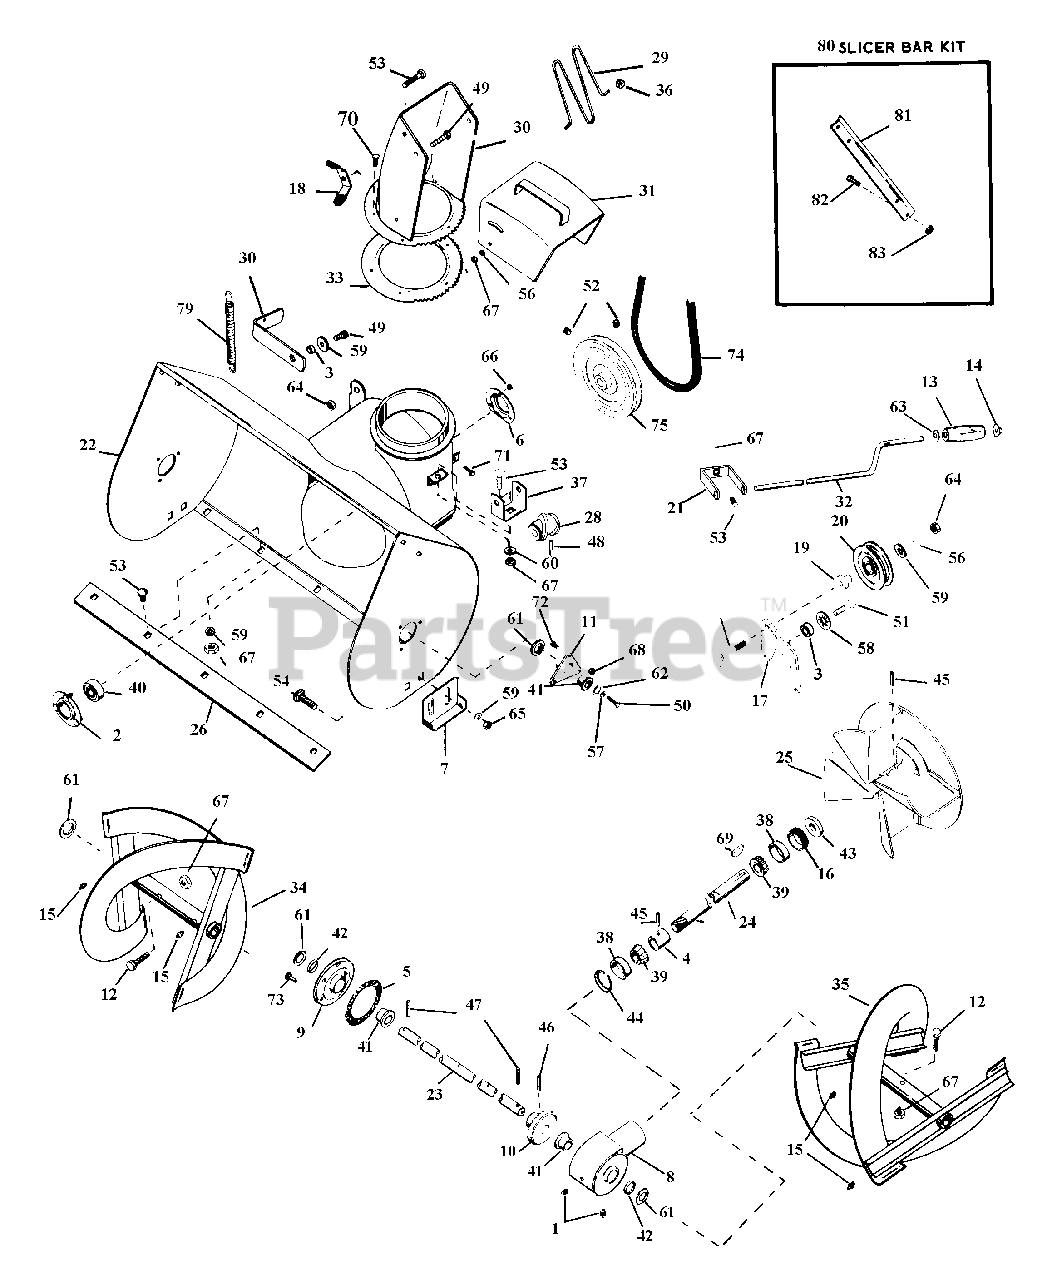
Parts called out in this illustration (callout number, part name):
1	PIPE PLUG
2	BEARING FLANGE
3	SPACER BUSHING .5 X .32 X .21
4	BEARING SPACER
6	BEARING FLANGE
7	RUNNER
8	CASE, GEAR - C.I.
9	GEAR CASE FLANGE
10	HELICON GEAR - 41 TOOTH
11	BEARING SUPPORT
12	SHEAR BOLT YWZC
14	CAP, 3/8 ROD YWZC
15	HYDRAULIC DRIVE FITTING
16	ADJUSTMENT PLUG
17	IDLER ARM
18	WING NUT, .312-18
19	SPCR, BRG .315X.50X.688X.281
20	IDLER
21	BRACKET
22	BLOWER HOUSING
23	FRONT GEAR SHAFT
24	SHAFT
26	SCRAPER BLADE
27	CLTCH LEVER
28	WORM GEAR
29	SAFETY WIRE
30	DISCHARGE CHUTE
31	DEFLECTOR CHUTE
32	CNTL CRANK
33	LOWER COLLAR GEAR
34	RAKE, RIGHT-20"(1ID X 13.88OD)
35	RAKE, LEFT-20"(1ID X 13.88OD)
36	FASTENER
37	WORM CLEVIS
38	BRG-CUP 1.781X.475
39	BRG-CONE .750X.61
40	BRG-BALL .750X1.750X.50
41	BSHG-FLG 1.000X1.12X.62X1.50BR
42	SEAL 1.000X1.312X.150
43	SEAL .750X1.499X.225
44	RG-RTNG INT 1.781 HSG X.062
45	PIN-ROLL .250X1.25
46	PIN-ROLL .313X1.38
47	PIN-ROLL .188X1.50
48	PIN-ROLL .125X.75
49	BLT-HEX .31-18X.75 PL GR2
50	BLT-HEX .50-13X1.00 PL GR2
51	BLT-HEX .31-18X.50 PL GR2
52	SCR-SET .32-18X.38 SKHCUPNL OH
53	BLT-RDHDSQSHNK .31-18X.50 YZ
54	BLT-RDHDSQNK .38-16X.75 SHT PL
55	BLT-RDHDSQNK .31-18X1.38SHT PL
56	WSHR-LK .312X.097 PL HVY
57	WSHR-LK .500X.151 HVY PL
58	WSHR-LK-INT .313X.030 PL
59	WSHR-FL-STL .38X.875X.083 PL
60	WSHR-FL-STL.312X.734X.065PL
61	WSHR-FL-STL 1.010X1.505X.062PL
62	WSHR-FL-STL .511X1.441X.125 PL
63	WSHR-FL-STL .382X.812X.023 PL
64	NUT-HEX .312-18
65	NUT-LK-CTR .375-16 GR A PL
66	NUT-LK-CTR .250-20 PL
67	NUT-LK .312-18 GR A PL
68	NUT-LK-FLG .250-20 PL
69	KEY-WDRF .188X.75X.313 SAE 9
70	RVT-POP.125 X .357 DOME PL
71	BLT-SCRHFWH .38-16X.50 PL
72	SCR-SLTR-SERNK .25-20X.62 PL
73	BLT-SERHFWH .25-20X.75 PL
74	V-BELT, 4L-WRAPPED
75	PLY-? 8.0X.75
76	SNO-THRO HELICON PATENT LABEL
77	CAUTION LABEL
78	IN OUT LABEL
79	SG-TENS .125X.437X5.5 WLD 20
